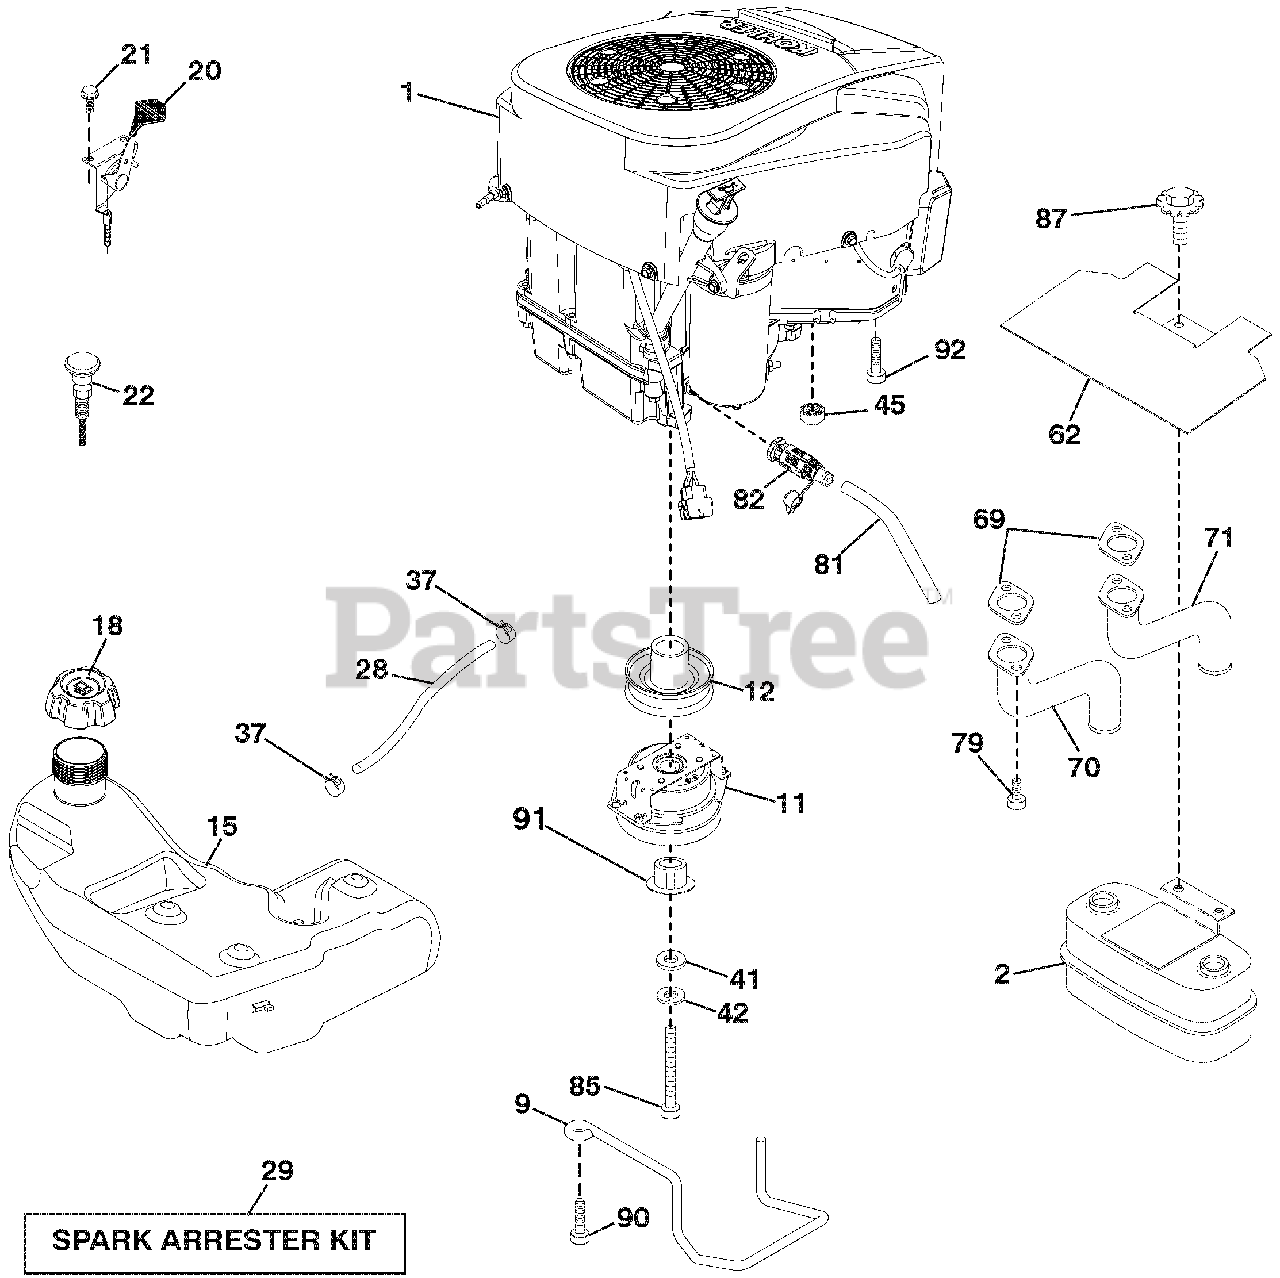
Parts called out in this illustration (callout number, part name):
1	ENGINE KOHL MODEL NO. SV601-3242 (586148801) (ORDER PARTS FROM ENGINE MANUFACTURER)
2	MUFFLER
9	KEEPER.BELT.ENGINE
11	ELECT. CLUTCH
12	PULLEY.ENGINE.TUFFTORQE.1"CRK.
15	TANK.FUEL.2.5.GAL.
18	CAP.FUEL
20	CONTROL THROTTLE/CHOKE
28	LINE.FUEL.22"FRONT.EMIS.CA.LP
29	KIT.SPARK ARRESTOR(392390 B&S)
37	CLAMP.HOSE.BLK.
41	WASHER.1-1/2 ODX15/32 IDX.250
42	WASHER.LOCK.HVY HLCL.SPR.7/16
45	Nut, Keps Hex 1/4-20 unc
69	GASKET.KOHLER.SV.I.
81	TUBE.DRAIN.OIL.EASY
82	VALVE OIL DRAIN
86	SCREW SOCKET HEAD 5/16-18 X 1
87	BOLT.5/16-18UNCX3/4 W/SEMS.BLK
90	SCREW.3/8-16X1.SMGML.TAP/R.BLK
92	SCREW.3/8-16 X 1.SMGML.TAP/R
94	TUBE.EXHAUST (ENGINE)
96	WASHER.9/32 X 7/8 X 16GA.
97	SCREW.HEXWSH.THDROL.1/4-20X3/4
138	PURGE.LINE.CARB
